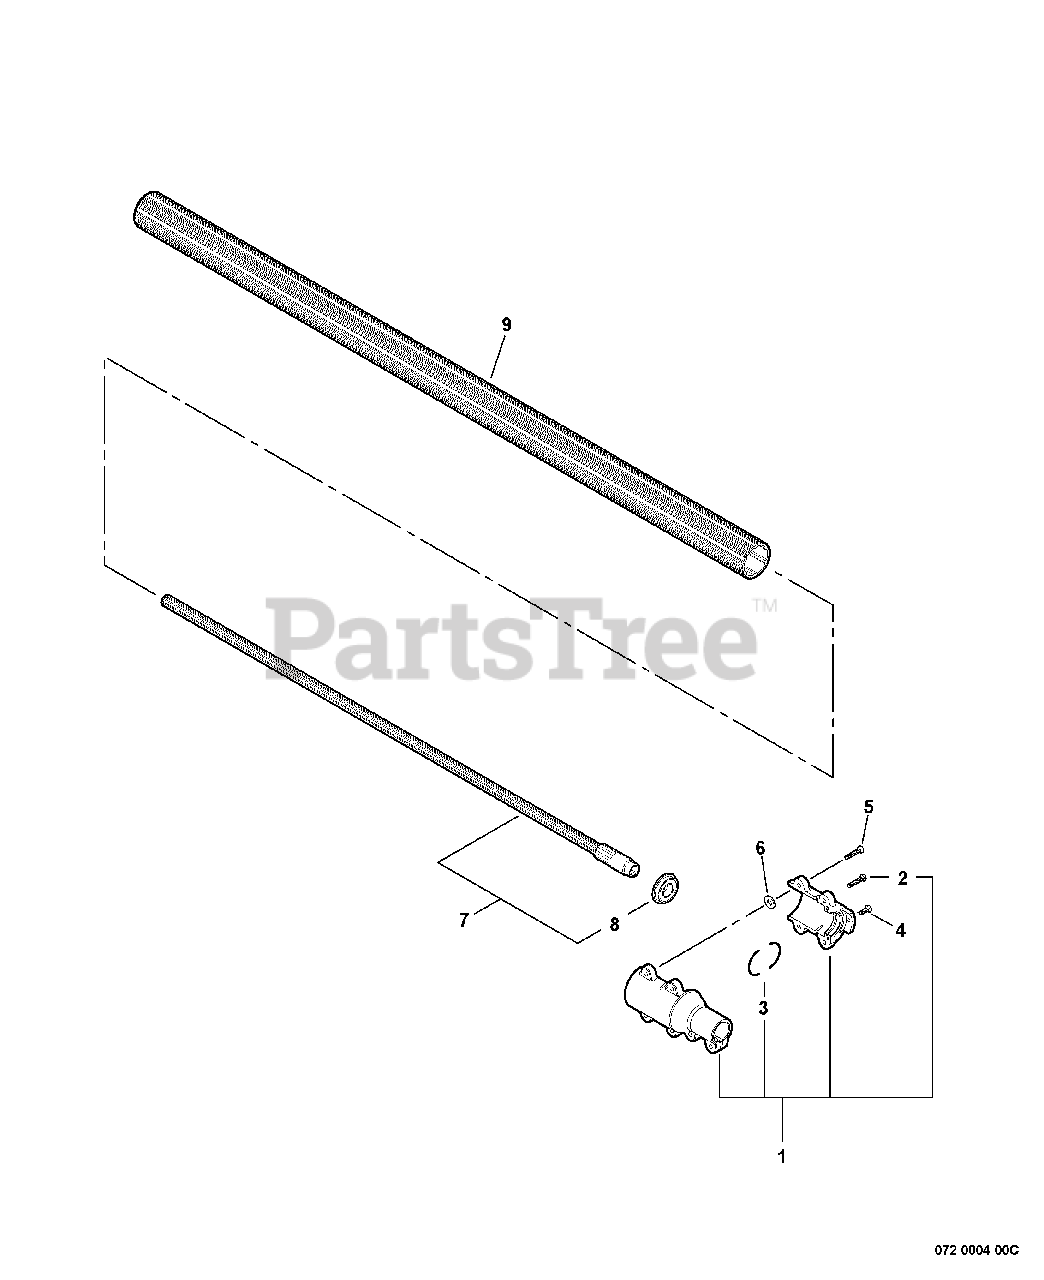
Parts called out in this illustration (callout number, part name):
1	COUPLING ASSY, LOWER
2	BOLT 5×20
3	CUSHION
4	BOLT 5×14
5	BOLT 5×20
6	WASHER 5
7	SHAFT ASSY, DRIVE
8	BEARING, BALL 15×32×9
9	PIPE, MAIN - ORANGE
